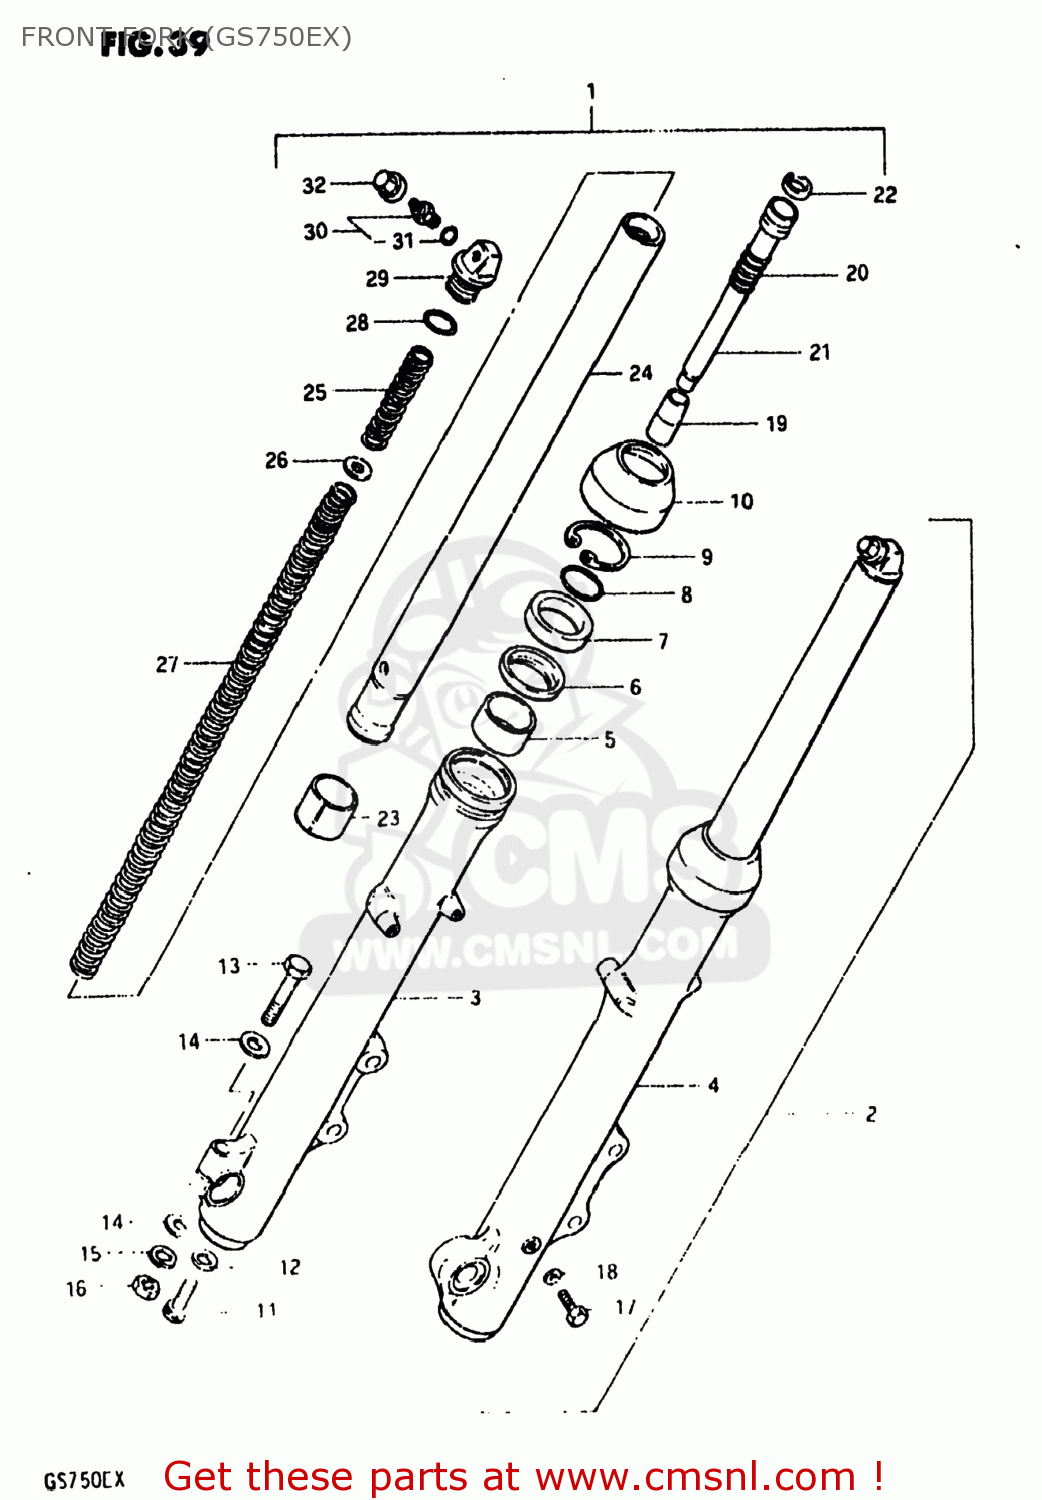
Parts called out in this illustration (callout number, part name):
1	DAMPER ASSEMBLY,RIGHT
2	DAMPER ASSEMBLY,LEFT
3	TUBE,FORK,OUTER,RIGHT
4	TUBE,FORK,LEFT,OUTER
5	BUSH,GUIDE
6	SPACER,SEAL
7	OIL SEAL,FRONT FORK
8	RING,FR FORK
9	CIRCLIP,FORK OIL SEAL
10	BOOT
11	BOLT(8X27)
12	GASKET (NAS)
13	BOLT 8X50
14	WASHER
15	LOCK WASHER
16	NUT
17	BOLT(6X8)
18	GASKET,DRAIN,PLUG (NAS)
19	PIECE,OIL LOCK
20	SPRING,FORK REBOUND
21	CYLINDER,FRONT FORK
22	RING
23	PISTON
24	TUBE,FORK,INNER
25	SPRING,FRONT FORK
26	WASHER,SPRING
27	SPRING
28	O-RING
29	BOLT,FORK INNER TUBE
30	VALVE,AIR
31	O-RING
32	CAP
